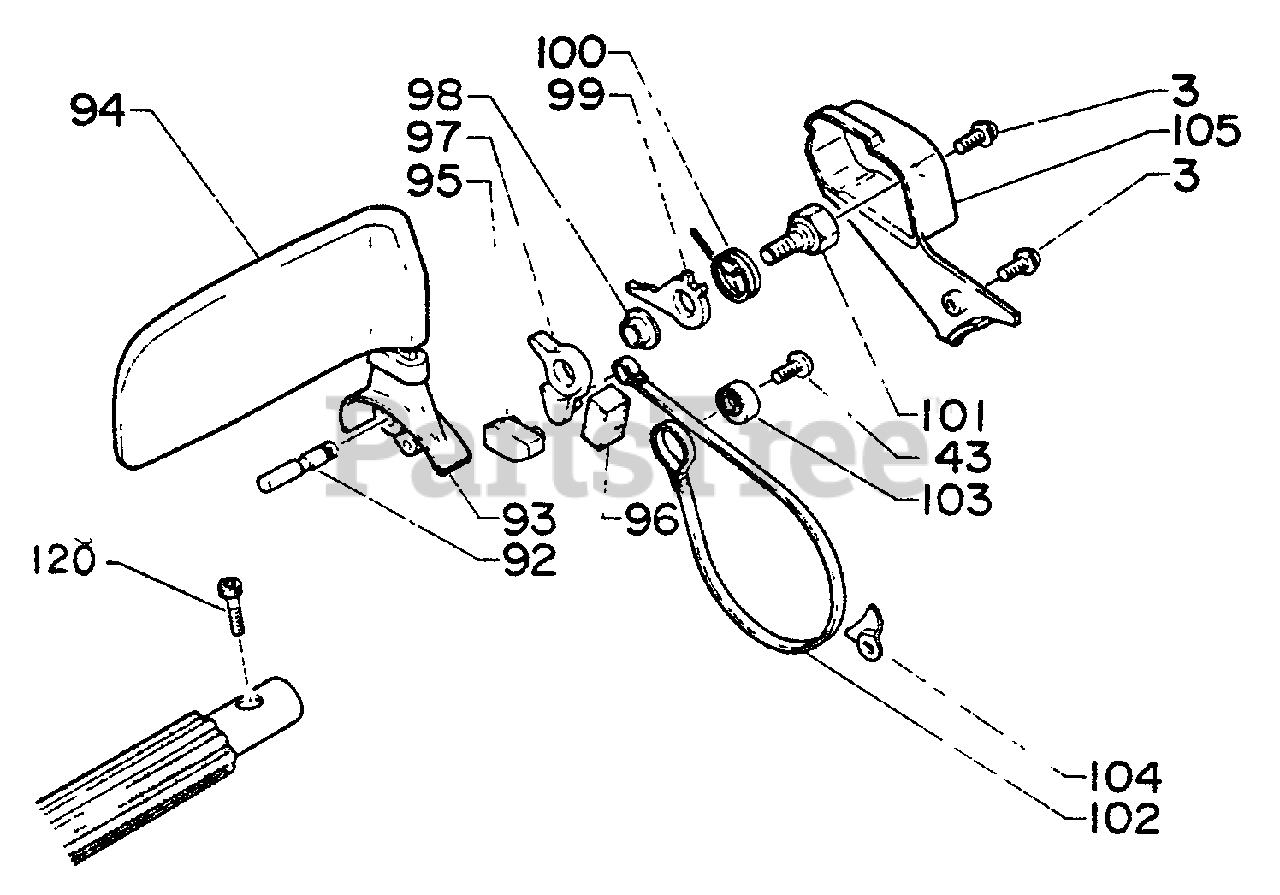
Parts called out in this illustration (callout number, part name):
3	SCREW - 4X12
93	COVER, BRAKE
94	HANDLE
95	RESET, BRAKE
96	SEAL
97	CONNECTOR
100	SPRING, RETURN
102	BAND, BRAKE
103	ADJUSTER, BRAKE BAND
104	RETAINER, BRAKE BAND
120	SCREW - 5X25
